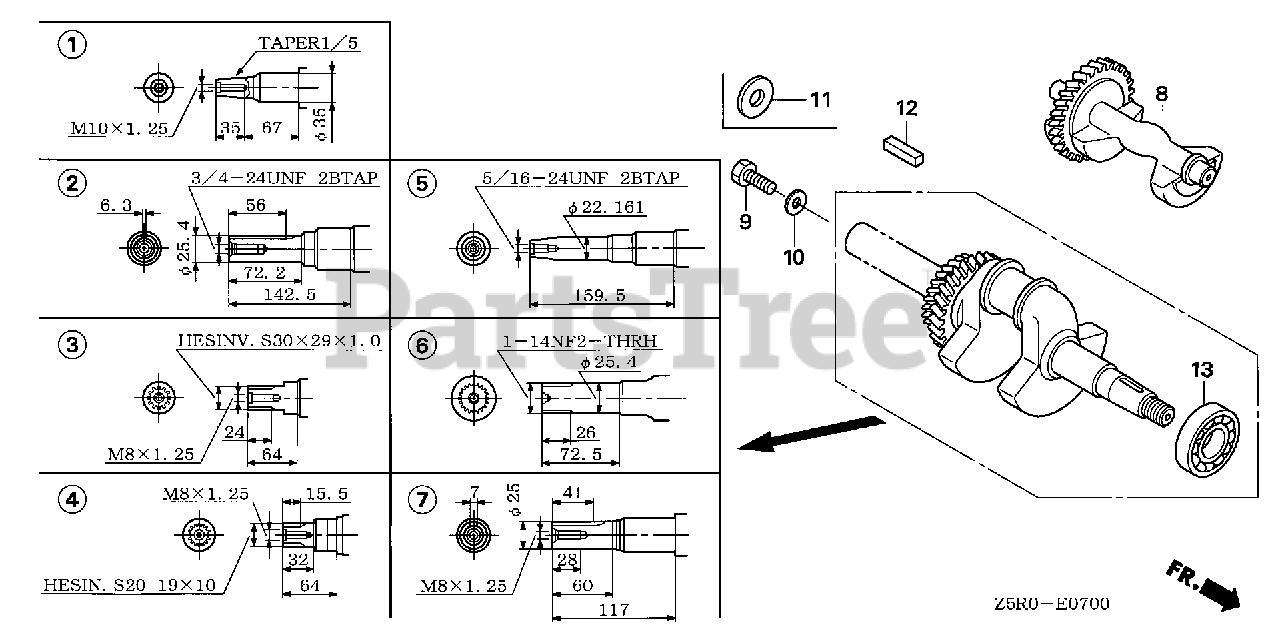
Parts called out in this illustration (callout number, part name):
6	CRANKSHAFT
8	WEIGHT, BALANCER
13	BEARING, RADIAL BALL (6207SH)
